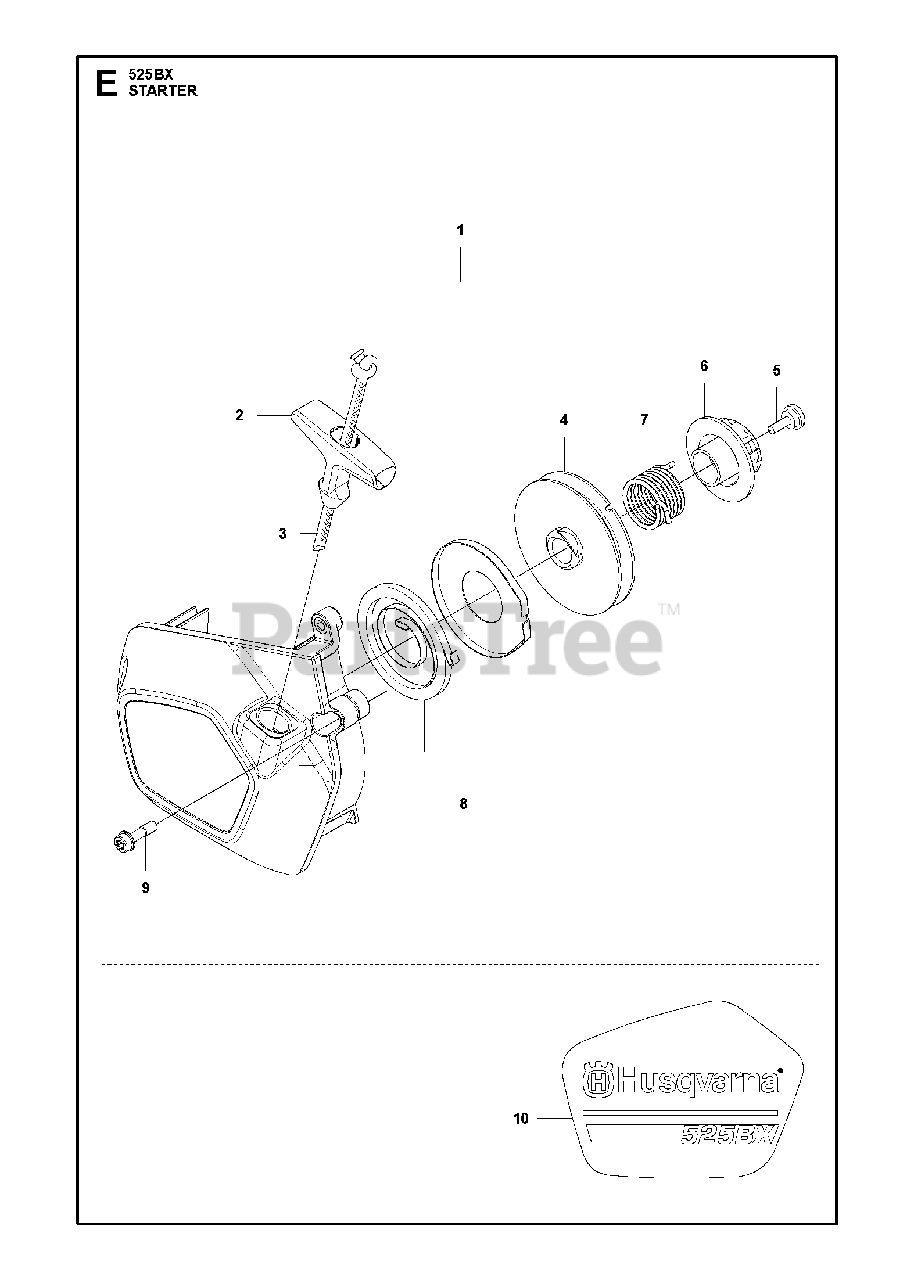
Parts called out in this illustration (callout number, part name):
1	STARTER ASSY
2	STARTER HANDLE
3	ROPE
4	REEL
5	SCREW
6	CAM PLATE
7	SPRING DAMPER
8	SPRING ASSY
9	BOLT
10	LABEL BRAND
